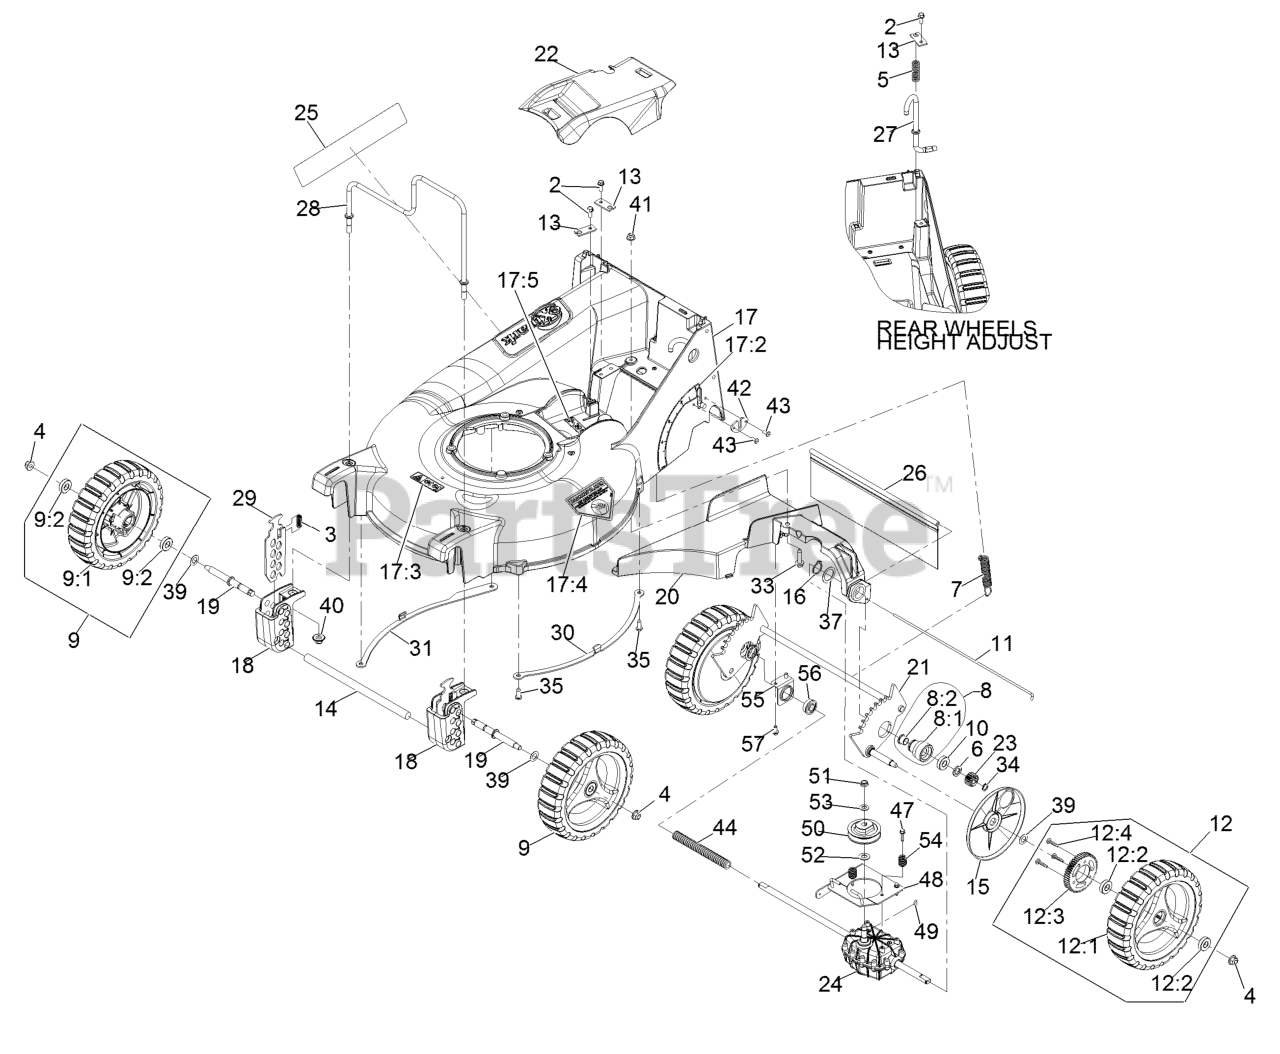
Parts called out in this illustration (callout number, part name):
2	SCREW-HWH
3	SPRING-COMPRESSION
4	NUT-HF, NI
5	SPRING-COMPRESSION
6	SPACER-BUSHING
7	SPRING-EXTENSION
8	HOUSING ASM
8:1	HOUSING-BEARING
8:2	BEARING-FLANGE
9:2	BEARING-BALL
10	BEARING-BALL
11	ROD,SHIELD
12:2	BEARING-BALL
12:4	SCREW-DRIVE
13	BRACKET,MOUNT
14	ROD,BUMPER
15	COVER,GEAR
16	RING-RETAINING
17	DECK W/DECALS
17:2	DECAL-HEIGHT OF CUT
17:3	DECAL-WARNING, BLADE
17:4	DECAL-DANGER
17:5	DECAL-DANGER
18	BLOCK,FRONT QUADRANT
19	AXLE-WHEEL
20	BRACKET-TRANSMISSION AND
21	WLD,REAR AXLE P21
22	COVER,BELT
24	TRANSMISSION-HD, 4.5/1
25	DECAL-COMM 21 X-SERIES
26	SHIELD-TRAILING P21
27	ROD-HEIGHT ADJ P21
28	GUARD,ENGINE
29	PLATE, FRONT HEIGHT
33	SCREW-HWHTF
34	RING-RETAINING
35	SCREW-BHTF
39	WASHER-PLAIN
40	Nut-Nyloc 3/8-16 Flg
41	NUT-HF, NI
42	PLATE,WEAR
43	RIVET-BLIND
44	COVER-SHAFT-DRIVE
47	SCREW-SPECIAL
48	TRANSMISSION PLATE ASM
49	KEY-WOODRUFF
51	NUT-HEX
52	WASHER-THRUST
53	WASHER-FLAT
54	SPRING,COMPRESSION
56	BEARING-BALL
57	SCREW-HWH
